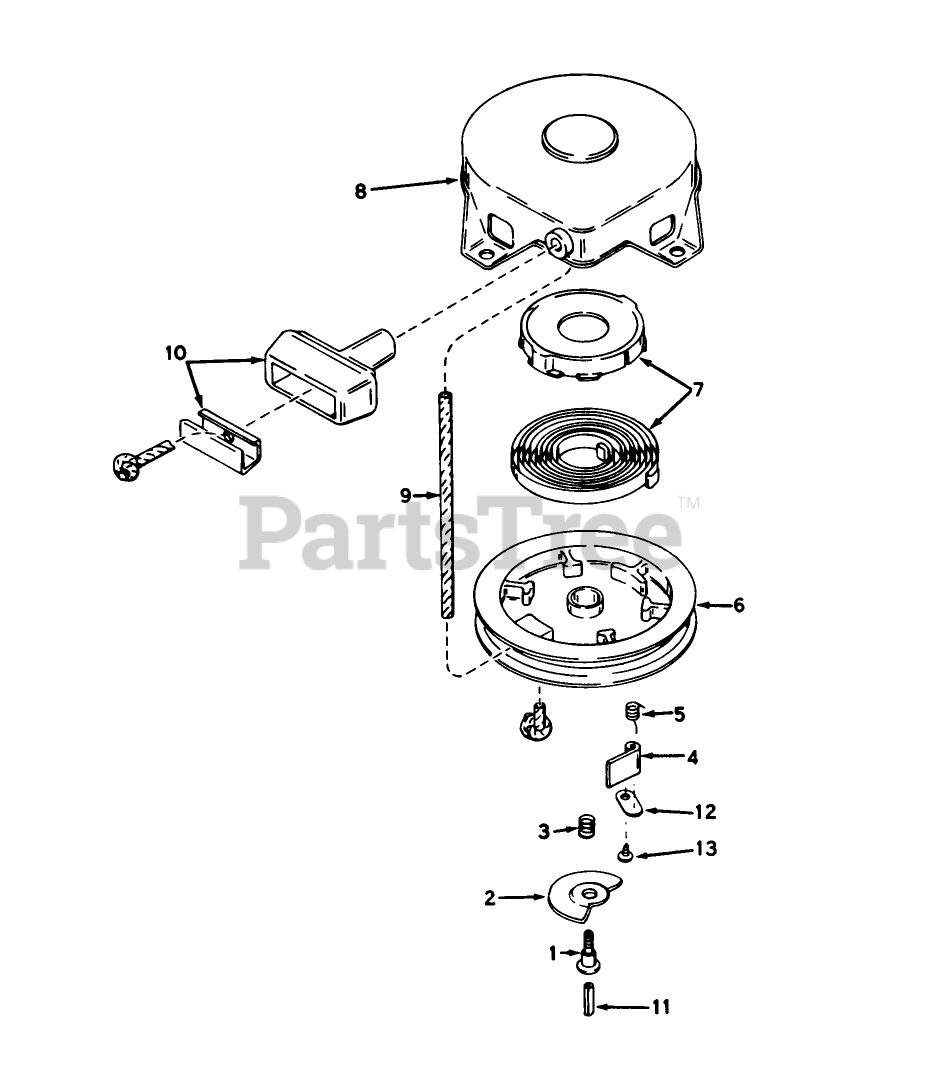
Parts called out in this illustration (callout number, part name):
1	Screw
2	Cam-Dog
3	Spring-Brake
4	Dog-Starter
5	Spring-Dog
6	Pulley
7	Spring Keeper Assy
8	STARTER HOUSING ASSY
9	Rope, Starter
10	Assy., Starter
11	Centering
12	Retainer-Dog
13	Screw
